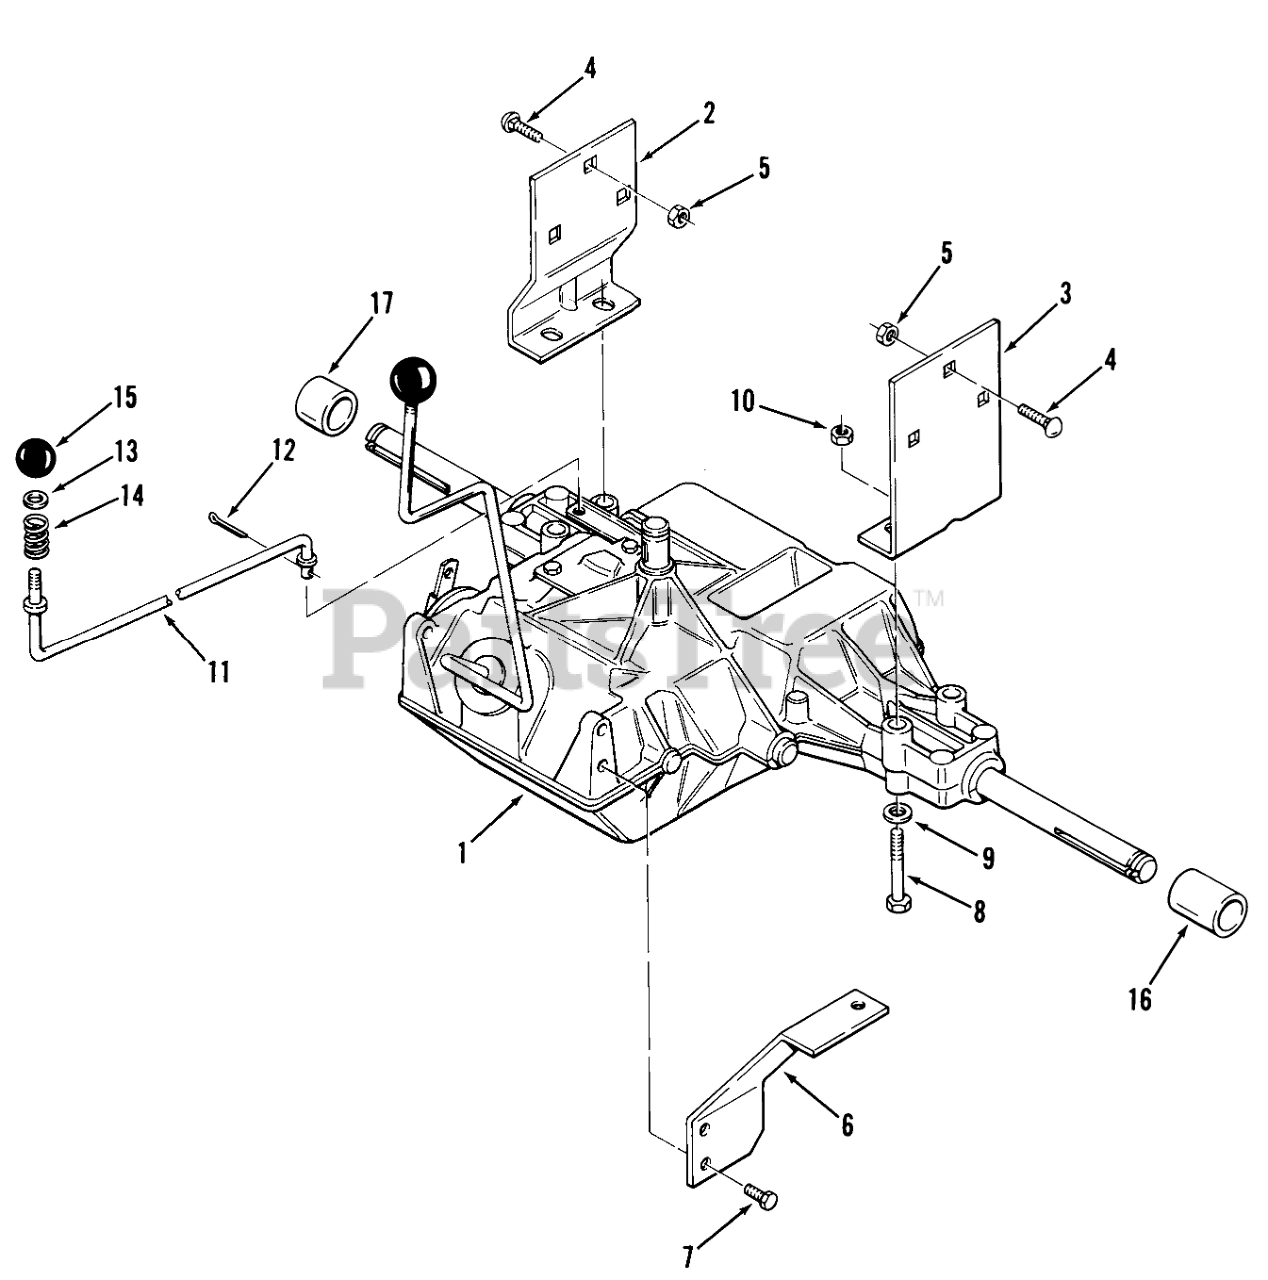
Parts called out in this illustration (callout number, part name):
1	Transmission-Foote Model 4000-5
2	Bracket-Rear Axle RH
3	BRK-TRANS MTG LH
4	CARRIAGE BOLT -4
5	Nut
6	Torque Strap
7	Bolt
8	Bolt
9	Washer
10	Nut
11	ROD-HI/LO SHIFT
12	Cotter Pin
14	Spring
15	Knob
16	Axle Spacer LH
17	Axle Spacer RH
